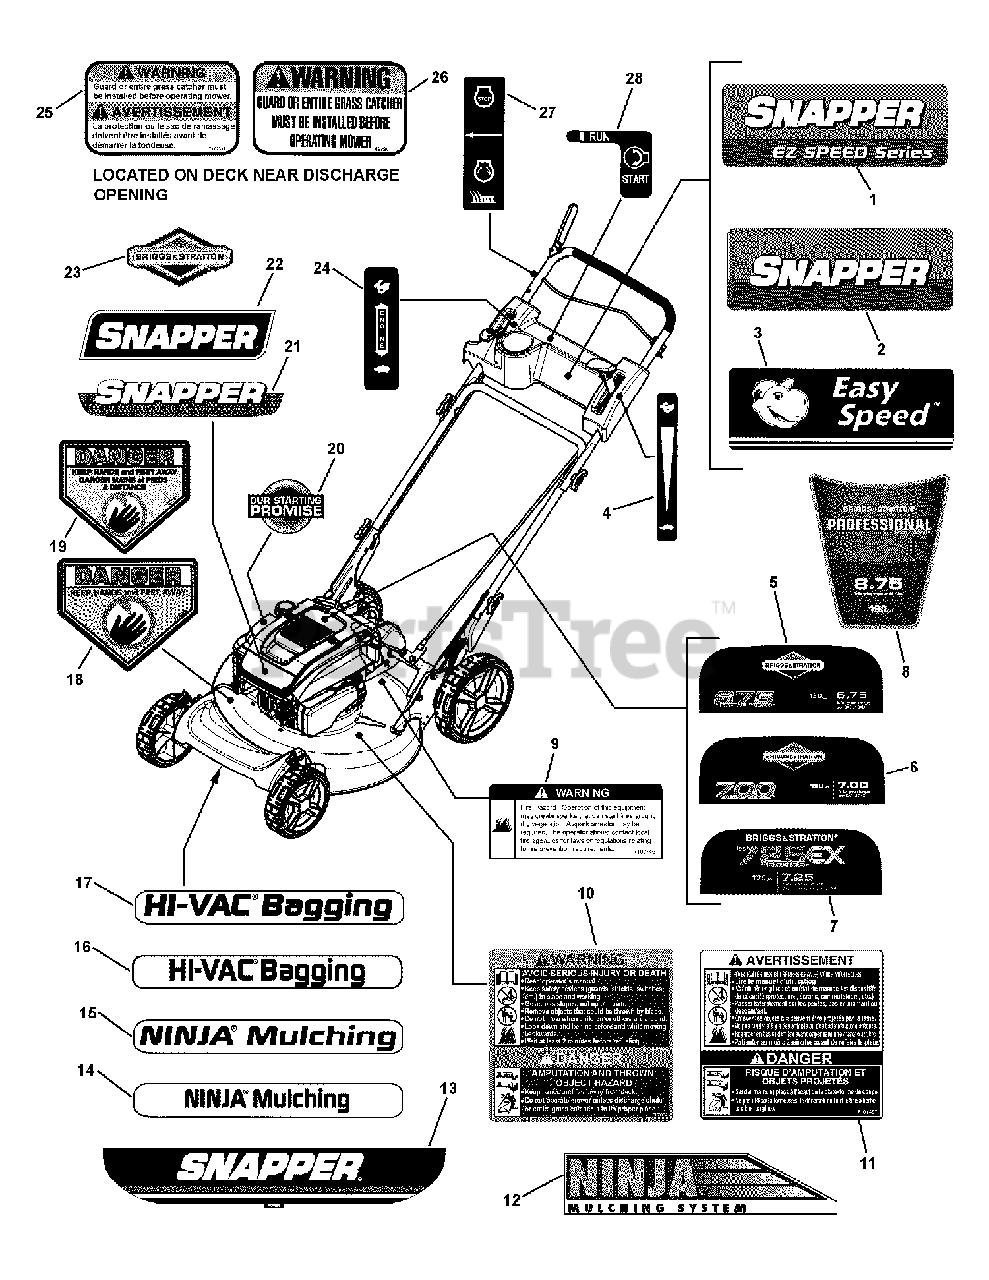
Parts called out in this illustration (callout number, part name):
1	DECAL, Easy Speed, Control Panel
2	DECAL, Snapper Control Panel
3	DECAL, Easy Speed, Control Panel
4	DECAL, Speed Shift
5	DECAL, Briggs Engine, 675 Series
6	DECAL, Briggs Engine, 700 Series
7	DECAL, 725 Series
8	DECAL, Briggs Engine 8.75T/190cc Professional Series
9	DECAL, Spart Arrestor
10	DECAL, Warning/Danger Walk-Behind Mowers
11	DECAL, Warning/Danger, French/English
12	DECAL, NINJA Mulching System
13	DECAL, SNAPPER, Steel Decks
14	DECAL, Ninja Mulching, Front Cover
15	DECAL, Front Cover, Ninja Mulching System
16	DECAL, Front Cover, Hi-Vac
17	DECAL, Front Cover, Hi-Vac
18	DECAL, Danger, Cut Finger
19	DECAL, French/English, CPSC
20	LABEL, Starting Promise
21	DECAL, Briggs Engine, Snapper
22	DECAL, Logo, Snapper, 7.88 long
23	LABEL, Briggs & Stratton Logo
24	DECAL, Throttle Control, B&S
25	DECAL, Chute/Deflector, French Canadian
26	DECAL, Chute/Deflector
27	DECAL, OPC Bail (International Symbol)
28	DECAL, Ignition Switch
